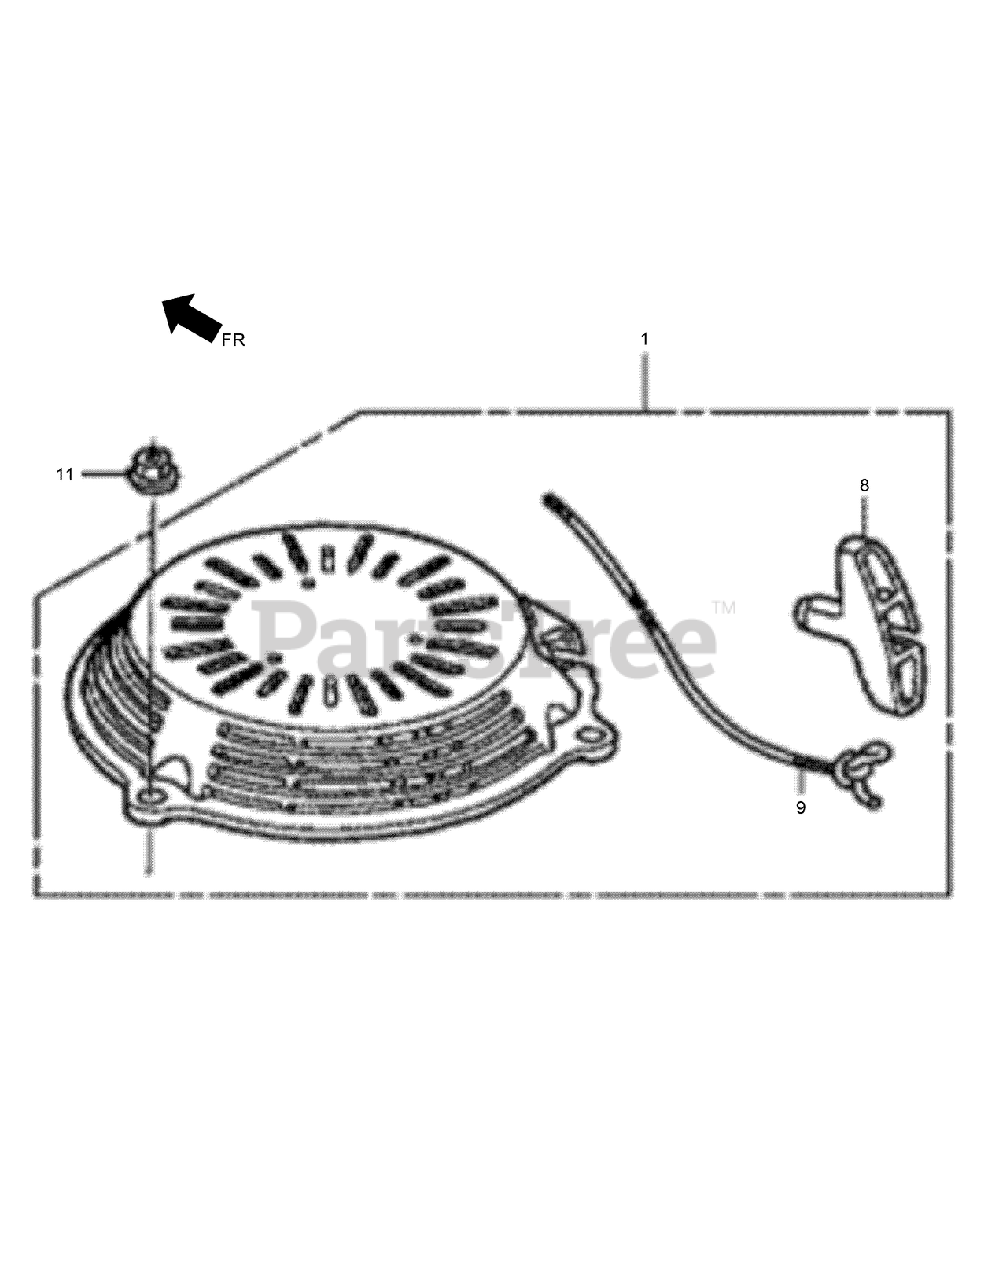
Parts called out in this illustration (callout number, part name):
1	STARTER ASM-RECOIL
8	GRIP-STARTER
9	ROPE-RECOIL STARTER
11	NUT-FLANGE-6MM
